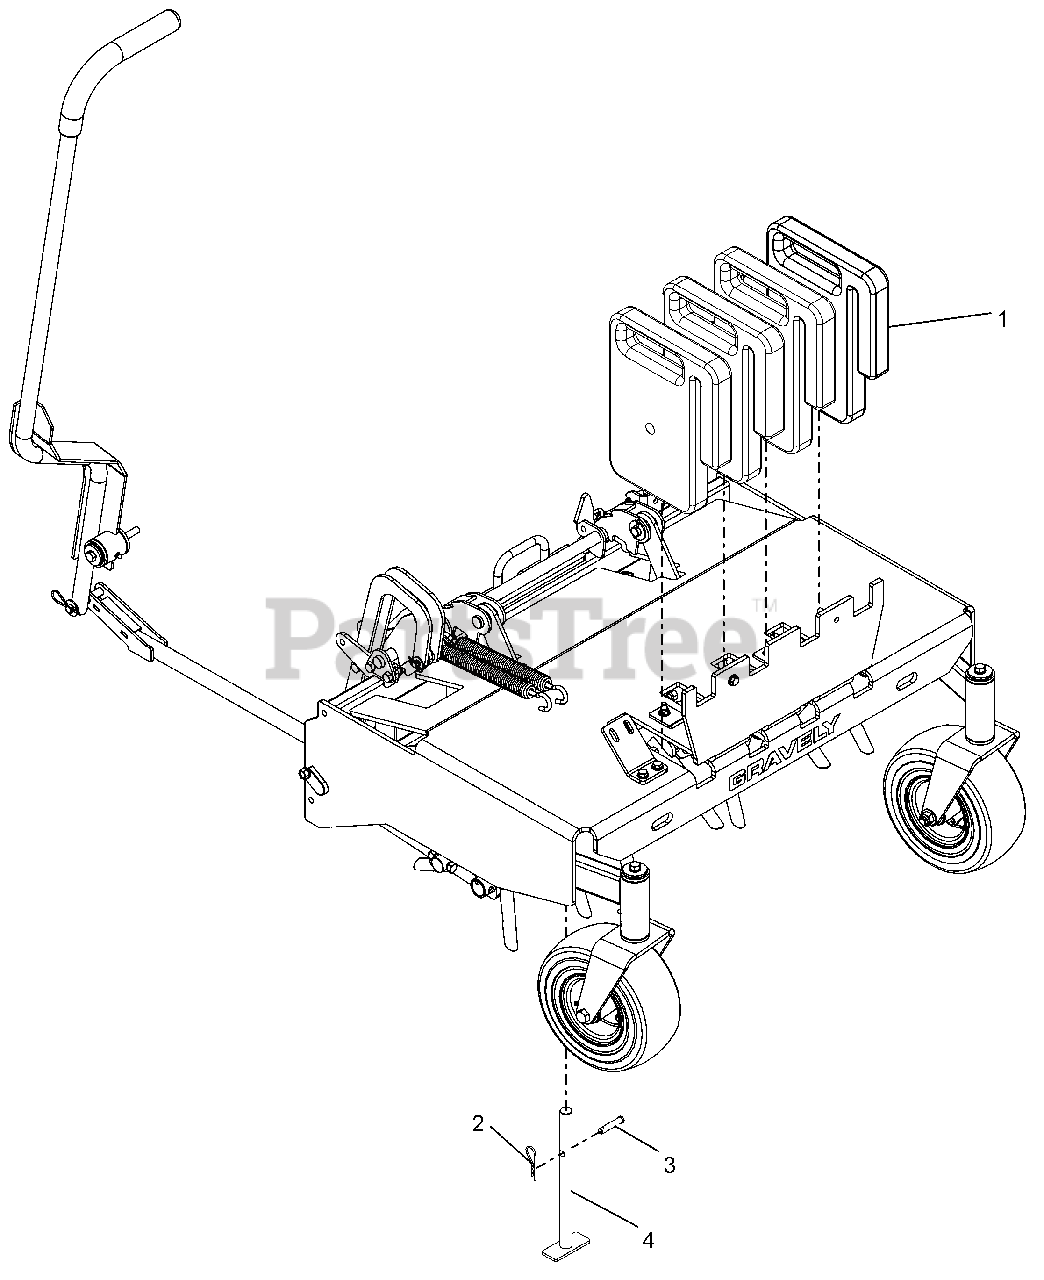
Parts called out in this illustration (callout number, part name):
1	WEIGHT, REAR
2	PIN, HAIR-#7 .094X2.31 ZC120
3	PIN-CLEV .370X1.75
4	WLDT, STAND
